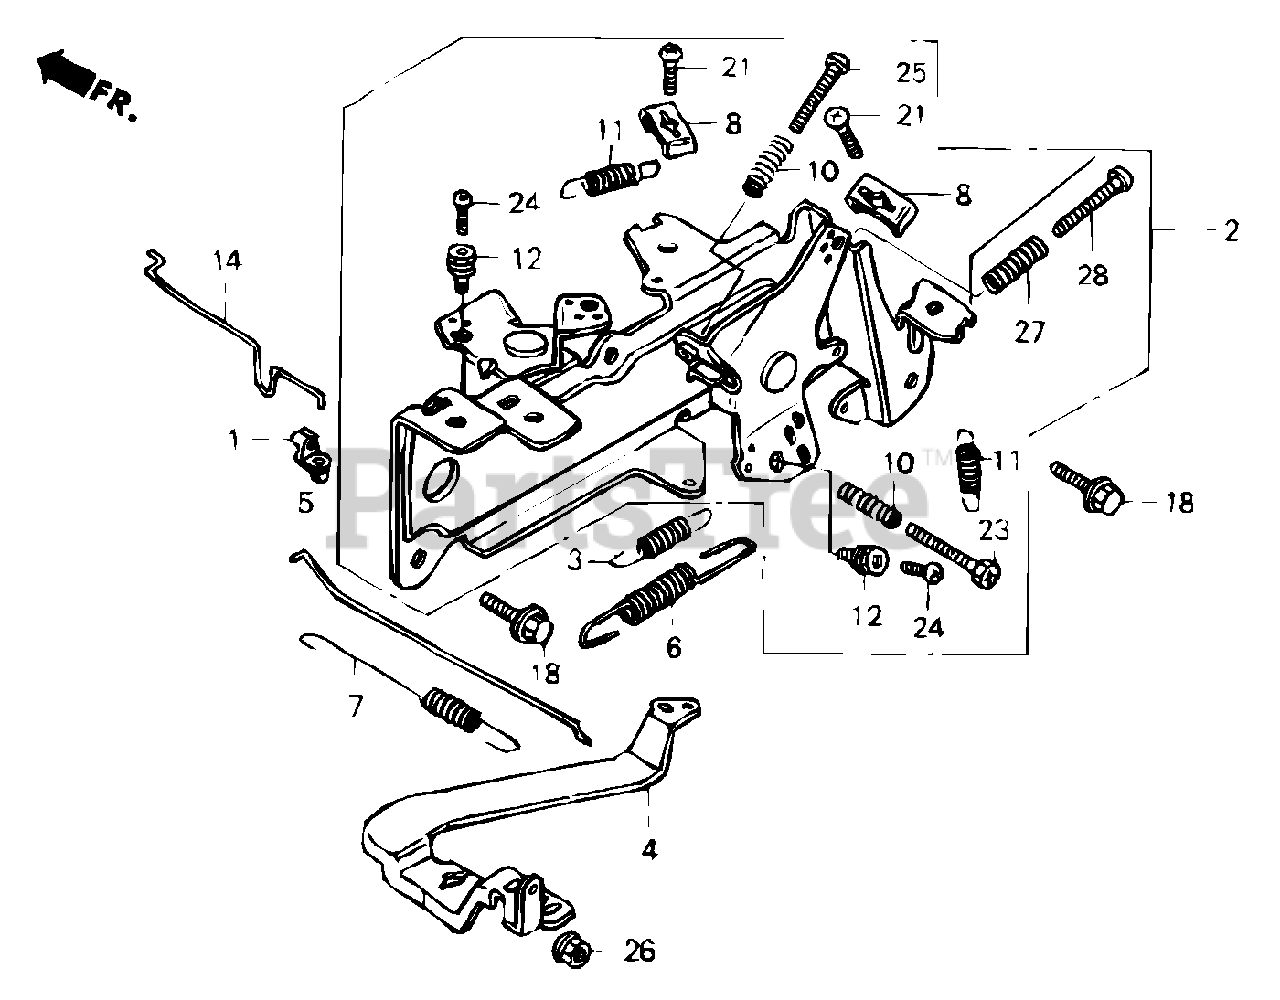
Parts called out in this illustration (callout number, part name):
1	Joint, Rod
2	Control Assembly
3	Spring, Starter
4	Arm, Governor
5	Rod, Governor
6	Spring, Governor
7	Spring, Throttle Return
8	Holder, Cable
10	Spring, Control Adjusting
11	Spring, Cable Return
12	Holder, Cable
14	Rod, Choke Control
18	Bolt, Flange (6x14)
21	Bolt, Slot (5x16)
23	Bolt, Slot (5x25)
24	Bolt, Recessed (4x6)
25	Screw, Pan (5x25)
26	Nut, Flange (6mm)
